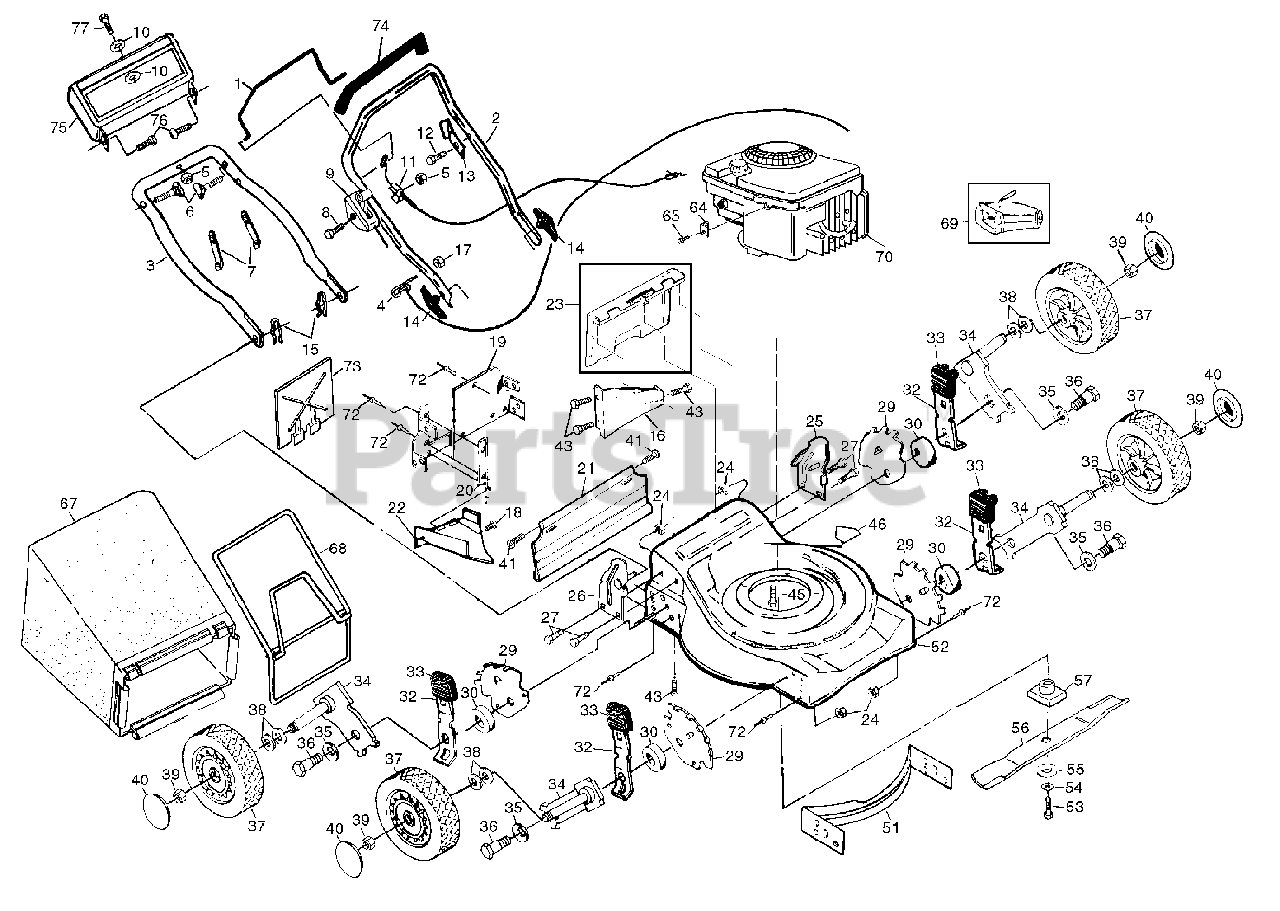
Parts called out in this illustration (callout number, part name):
1	Control Bar
2	Upper Handle
3	Lower Handle
4	Rope Guide
5	Locknut 1/4-20
6	Handle Bolt
7	Wire Tie
8	Machine Screw 1/4-20 x 2.12
9	Throttle Control
11	Engine Zone Control Cable
12	Hex Washer Head Screw #10-24 x 1/2
13	Up-Stop Bracket
14	Handle Knobs
15	Hairpin Cotter
16	Rear Baffle
17	Keps Locknut 1/4-20
18	Hex Head Screw
19	Back Plate
20	Side Baffle
21	Rear Skirt
22	Discharge Baffle
23	Rear Door Assembly Kit
24	Locknut 3/8-16
25	Handle Bracket Assembly (Left)
26	Handle Bracket Assembly (Right)
27	Screw 5/16-18 x 3/4
29	Wheel Adjusting Bracket
30	Spacer
32	Selector Spring
33	Selector Knob Deluxe
34	Axle Arm Assembly
35	Belleville Washer
36	Shoulder Bolt 3/8-16
37	Wheel Assembly
38	Washer
39	Locknut
41	Hinge Screw
43	Hex Tapping Screw 1/4-20 x 1/2
45	Hex Head Thread Rolling Screw 3/8-16x1
46	Danger Decal
51	Front Baffle
52	Housing Assembly
53	Hex Head Screw 3/8-24 x 1-3/8 Grd. 8
54	Helical Lock Washer
55	Hardened Washer
56	20" Blade
57	Blade Adapter
64	Cable Clamp
65	Screw #10 x 5/8
67	Grass Bag
68	Catcher Frame
69	MA36 Clipping Deflector
70	Engine - Briggs/Stratton
73	Mulcher Plate
74	Handle Grip
75	Trim Plate
77	Screw
